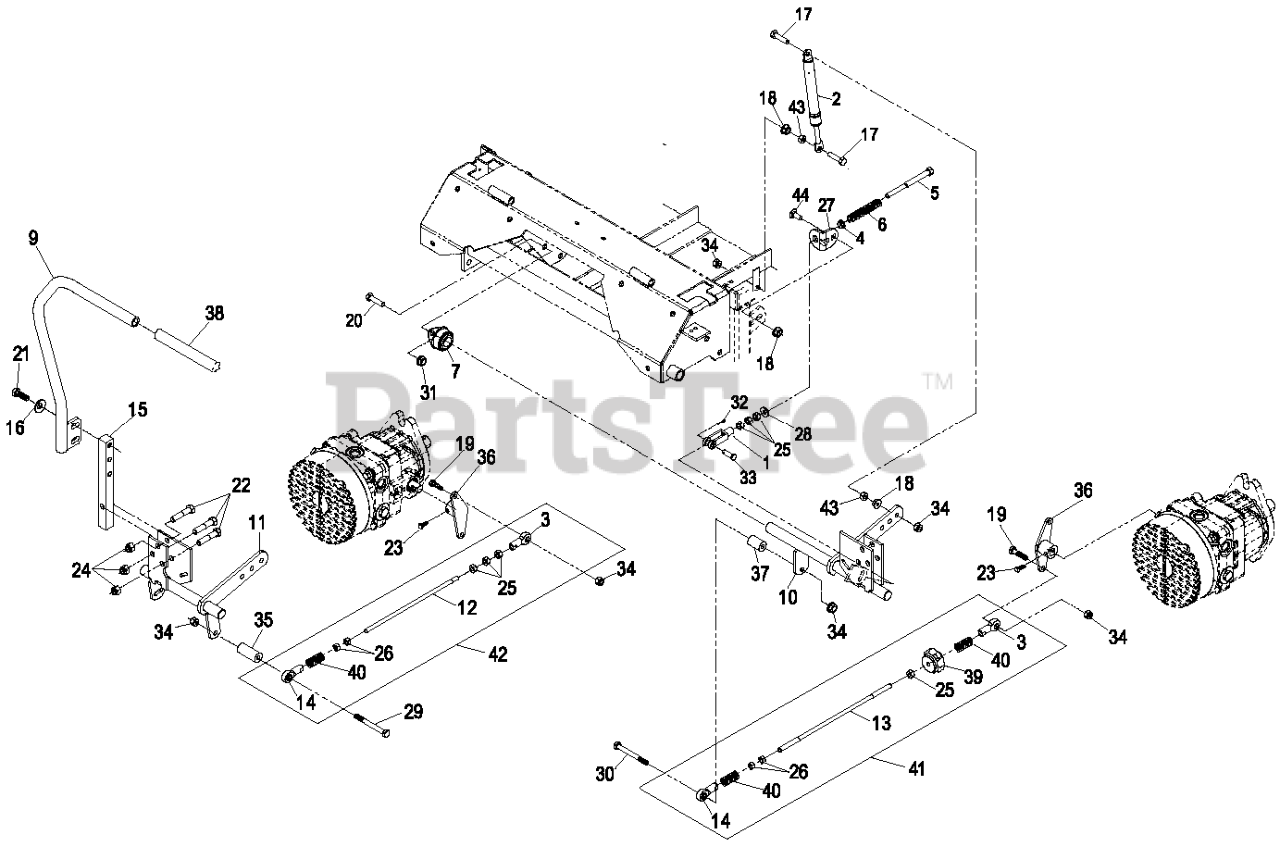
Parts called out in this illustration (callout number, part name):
1	YOKE-ADJUSTABLE
2	DAMPER-CONTROL, MOTION
3	BALLJOINT-RH
4	BUSHING-NYLON, FLANGED
5	BOLT-RETURN, NEUTRAL
6	SPRING-RETURN, NEUTRAL
7	BEARING-FLANGE, SIDE
9	ASM.RH LEVER/GRIP
11	CONTROL-MOTION, RH
12	LINK,XP HYDRO CONNECT RH
13	LINK,TRACKING ROD XP
14	BALLJOINT-LH
15	ARM-SHAFT, CONTROL
16	WASHER-BELLEVILLE
17	SCREW-HH
19	SCREW-HH
20	SCREW-HH
21	SCREW-HH
22	SCREW-HH
23	SCREW-SET
24	NUT-LOCK, NI
25	NUT-HEX
27	TAB-ADJUSTMENT
28	WASHER-FLAT
29	SCREW-HH
30	SCREW-HH
31	NUT-HHF, WHIZ
32	PIN-COTTER
33	PIN-CLEVIS
34	NUT-LOCK, NI
35	SPACER-CONTROL, HYD
36	ARM-CONTROL, HYDRO
37	SPACER-HYDRO CONTROL, LH
38	GRIP,CONTROL LEVER
39	KNOB-TRACKING
40	SPRING-COMPRESSION
41	TRACKING ROD ASM
42	RH HYD CONNECT LINK ASM
43	NUT-HEX
44	SCREW-CARR
